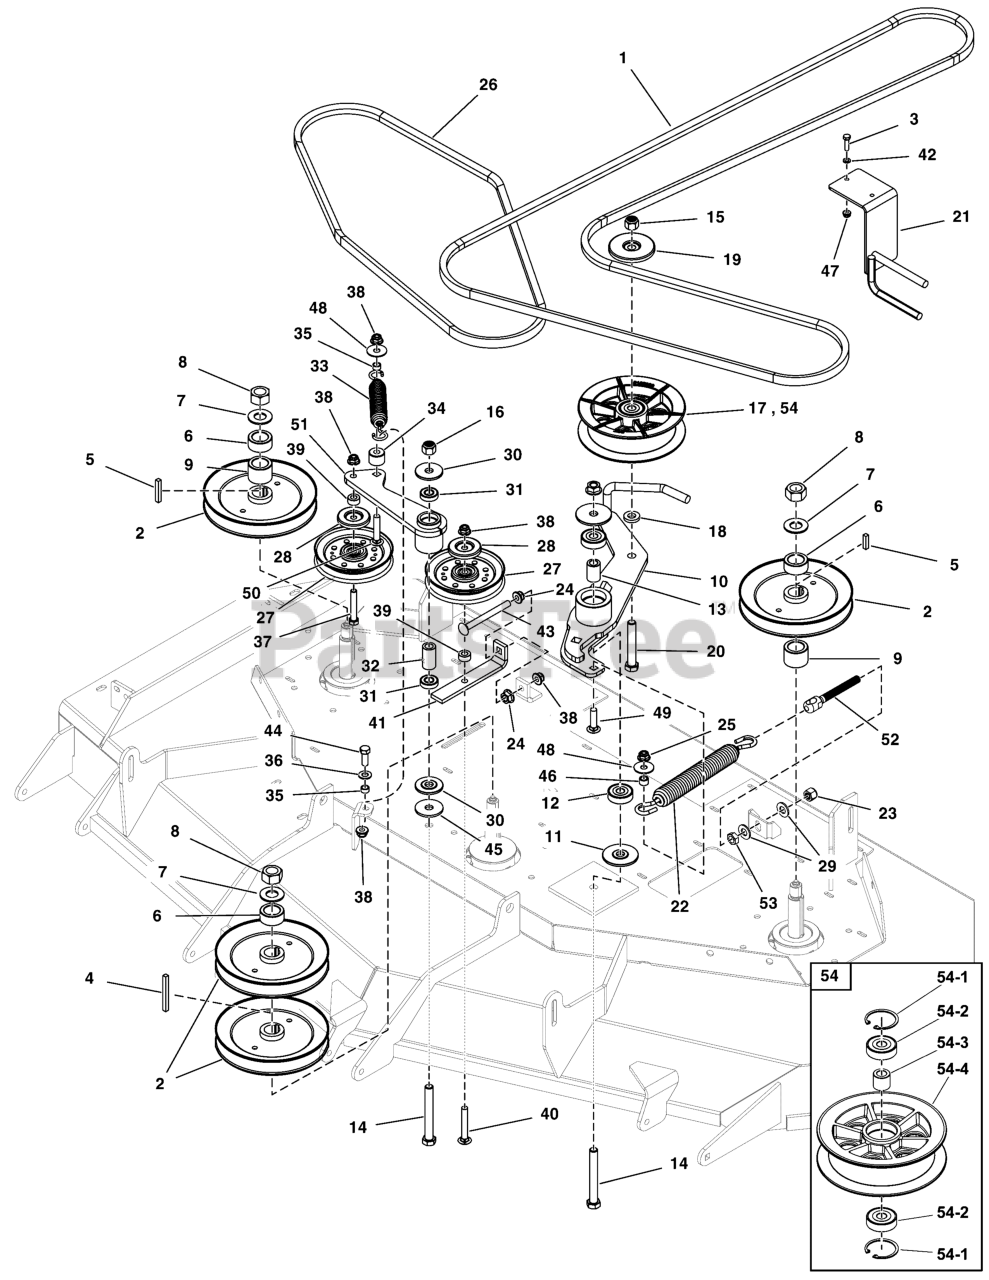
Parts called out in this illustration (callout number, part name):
1	BELT, 5V/SPB, 138.50 EL, LG ARAMID, WRPD
2	PULLEY, SPNDL, 7.032"OB X .985"ID
3	BOLT, 1/4-20 X 1" GD5 CZ
4	KEY, 1/4 SQ. x 2-1/4
5	KEY, 1/4 SQ X 1
6	SPACER, 1.00 X 1.50 X .70, BZ
7	WASHER, 3/4 BELLEVILLE CL/ZC
8	NUT, 3/4-16 Hex
9	SPACER, 1.00 X 1.50 X 1.14, BZ
10	WELD, IDLER ARM, DECK DRIVE - BLK
11	SPACER, IDLER ARM, 1/2 X 2.25
12	BEARING, 6203-1/2", SEALED
13	SPACER, .51 X .84 X 1.22, PM, CZ
14	BOLT, 1/2-13 X 4" GD5 CZ
15	NUT, 1/2-13 HEX NYLON LOCK
16	NUT, Hex Flange, Nylock, 1/2-13
18	SPACER, .52 X 1.00 X .22, PM, CZ
19	SHIELD, PULLEY, 1/2"ID X 2-7/8"OD, CZ
20	BOLT, 1/2-13 X 3-1/4, HEX HD, GD5, CZ (SV)
21	GUIDE, Belt
22	SPRING, EXT1.22"ODX10.5"FLX.192"WIRE BLK
23	NUT, Hex, Nylon Lock, 1/2-20
24	NUT, 3/8-16 Hex Large Serrated Flange
25	NUT, 3/8 - 16 HEX NYLOCK FLANGE
26	BELT, B-SEC, 64.00 EL, ARAMID, WRPD
27	PULLEY, V-IDLER, 5"OD X 3/8", CZ, TE
28	SHIELD, PULLEY, 3/8"ID X 2"OD, CZ
29	WASHER, 1/2 SAE
30	SPACER, IDLER ARM, 1/2, PM
31	BEARING, BALL, AXLE
32	SPACER, .52 X .84 X 1.53, PM
33	SPRING-EXT, 1.04 ODX6.935LGX.148WR, BLK
34	SPACER, .39 X 1.00 X .75, CZ
35	SPACER, .38 X .50 X .27, CZ
36	WASHER, 3/8 SAE
37	BOLT, 3/8-16 X 2-1/4" GD5 CZ
38	NUT, 3/8 - 16 HEX NYLOCK FLANGE
39	SPACER, .39 X 1.00 X .38
40	BOLT, 3/8-16 X 2-1/2, CARRIAGE, GD5, CZ
41	PLATE, IDLER PULLER - BLK
42	WASHER, 1/4 SAE
43	BOLT, 3/8-16 X 4-1/2, CARRIAGE, GD5, CZ
44	BOLT, 3/8-16 X 1" GD5 CZ
45	WASHER, .52 X 1.75 X .14, CZ
46	SPACER, .39 X .63 X .375M DOM CZ
47	NUT, 1/4-20 Hex Nylock Flange
48	WASHER, 3/8" Fender
49	BOLT, 3/8-16 X 1-1/2, CARRIAGE, GD5, CZ
50	BOLT, 3/8-16 X 2, CARRIAGE, GD5, CZ
51	WELD, IDLER ARM, 2 BELT DRIVE - BLK
52	SPRING PULLER, 1/2-20, 5.00
53	NUT, 1/2-20 Hex Jam
54	PULLEY, IDLER, 5.50, CI
54-1	SNAP RING, Internal
54-2	BEARING, 6203-3RC3-1/2SRI2-Q
54-3	SPACER, .505 X .875 X .805, CZ
54-4	PULLEY HOUSING
